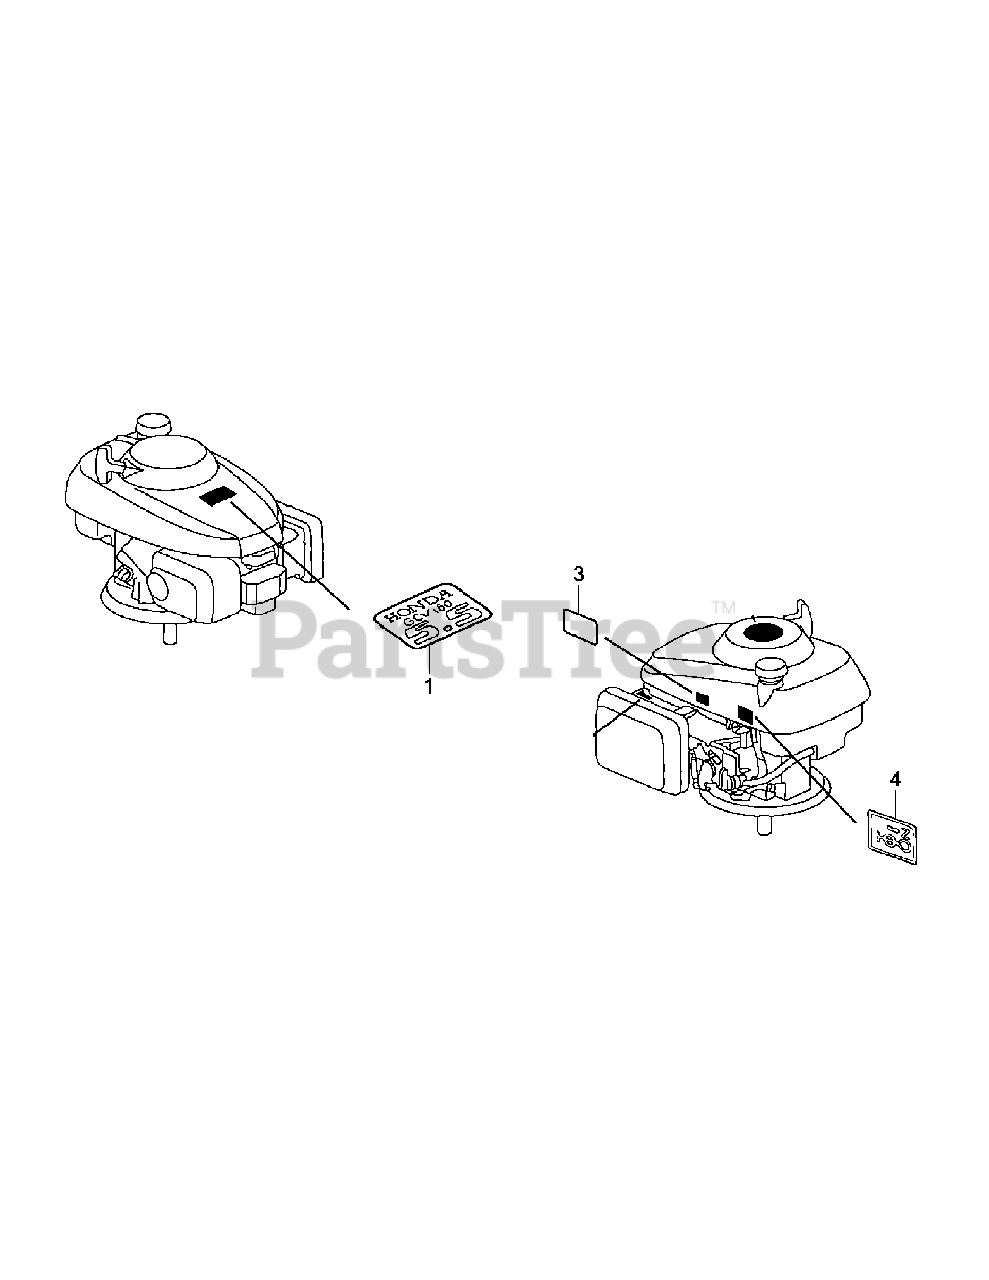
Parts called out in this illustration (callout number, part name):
1	Pri; Emblem (Gcv160 5.5)
3	Label, Warning
4	Mark, Choke
